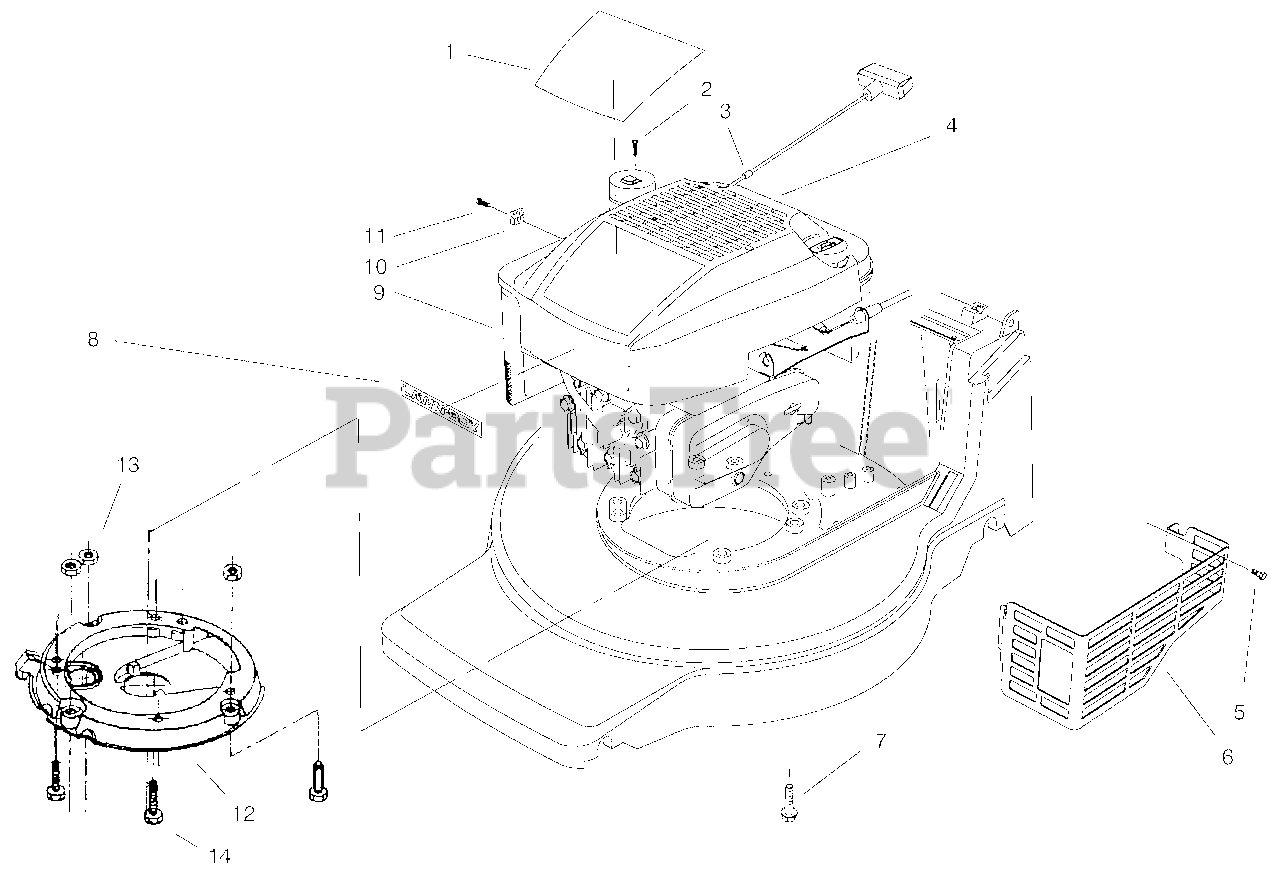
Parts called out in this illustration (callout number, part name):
1	Decal-Recoil
2	Screw-Mounting
3	Stop-Rope
4	Cover-XTE
5	Screw-Hex Washer Head Thread Forming
6	Shield-Muffler
7	Screw-Tapping
8	Decal-Shroud
9	Engine
10	Clamp-Casing
11	Screw-Clamp
12	Plate-Engine Mount
13	Nut-Lock
14	Screw-Hex Hd. Cap
